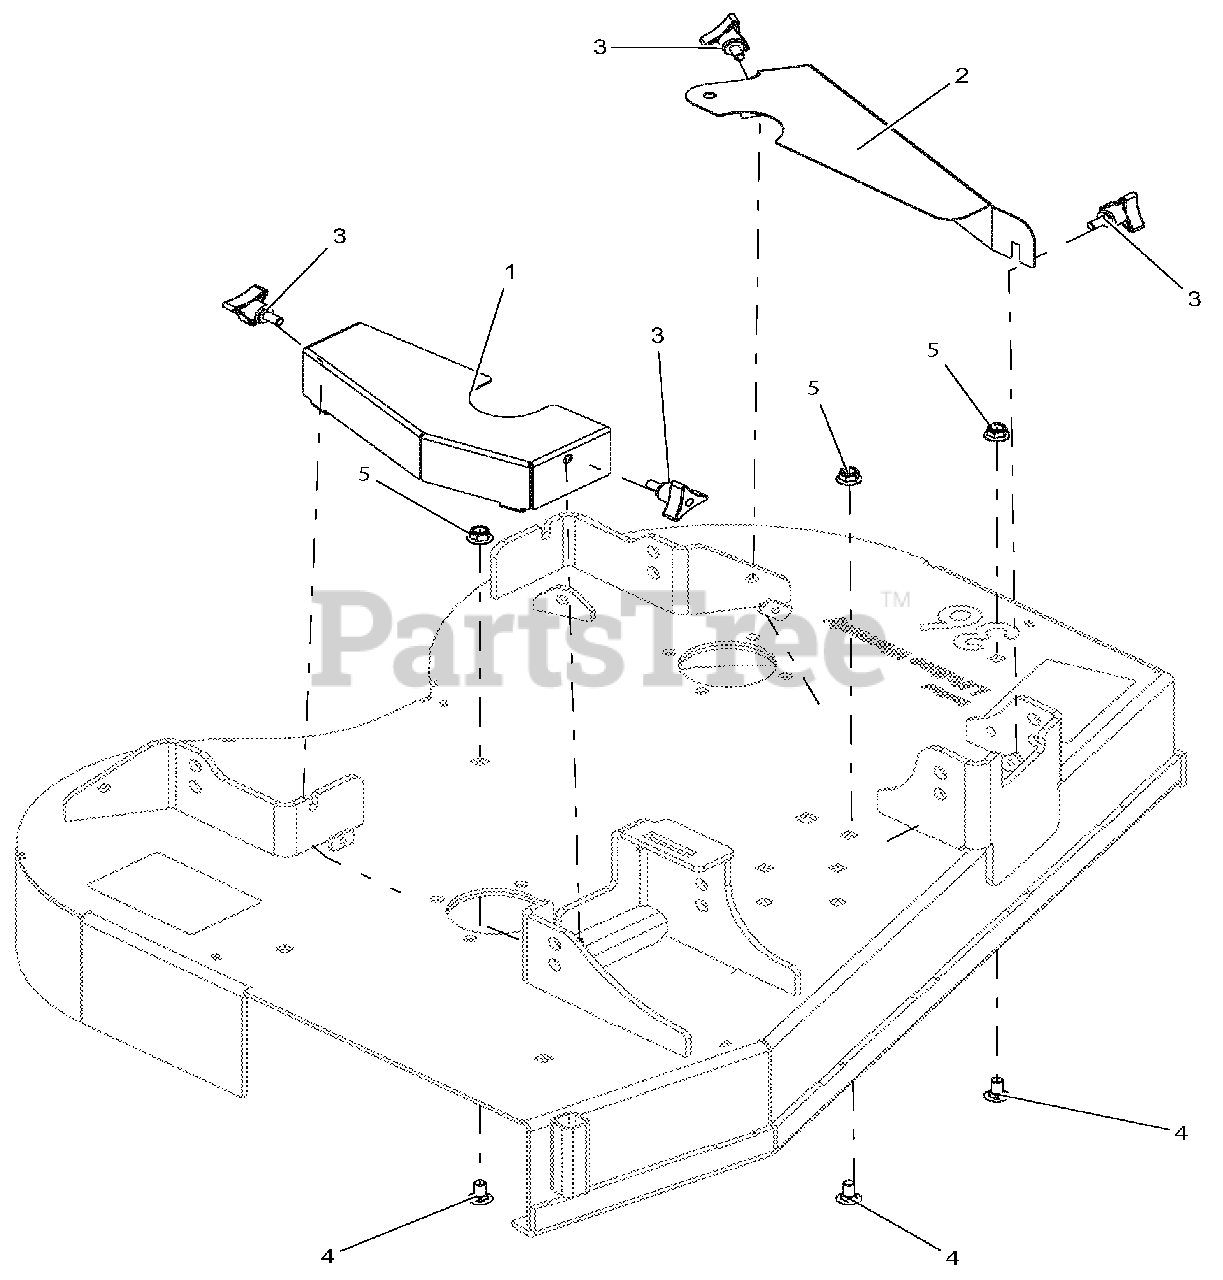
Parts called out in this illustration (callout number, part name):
1	WLDMT, GUARD RH SPINDLE
2	GUARD, LH SPINDLE
3	KNOB, WING STUD .312-18X.75
4	BLT-RDHDSQNK .38-16X.75 G5 YWZC
5	NUT-LK-NYL-FLG .38-16 YWZC
